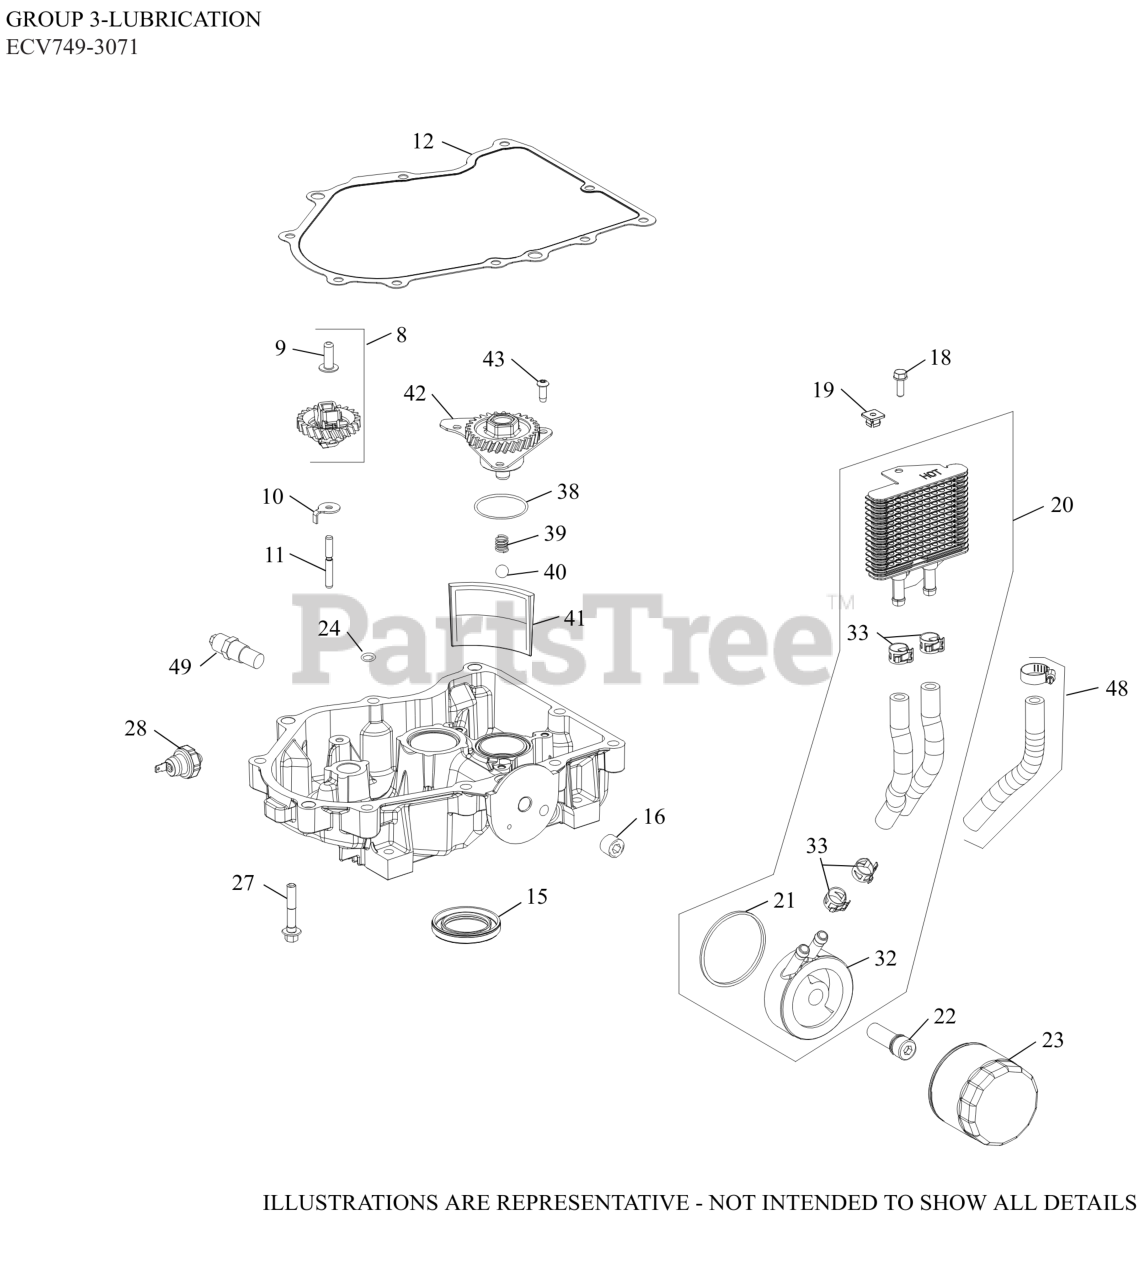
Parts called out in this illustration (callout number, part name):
8	KIT, GOVERNOR GEAR W/PIN
9	PIN, GOVERNOR REGULATING
10	TAB, LOCKING
11	SHAFT, GOVERNOR GEAR
16	PLUG, PIPE CTSK 3/8"
18	SCREW, TAP M6X1.7X18
19	NUT, PLASTIC - BLACK
20	COOLER, OIL & DIVERTER ASSEMBLY
21	O-RING, OIL COOLER
22	NIPPLE, OIL FILTER - (#2413608S)
23	OIL FILTER
24	O-RING (.5" DIA)
26	SCREW, HEX FLANGE
27	SCREW, FLG M8X1.25X45
28	SWITCH, OIL PRESSURE
32	ADAPTER, OIL FILTER (CV EFI)
33	CLAMP, HOSE LOW PROFILE
38	O-RING (1.78" DIA)
39	SPRING, COMPRESSION
40	PRESSURE RELIEF BALL
41	SCREEN, OIL
42	PUMP, OIL ASSEMBLY
43	SCREW, BUTTON HEAD
48	KIT, HOSE 140MM
49	SENSOR, OIL TEMPERATURE
